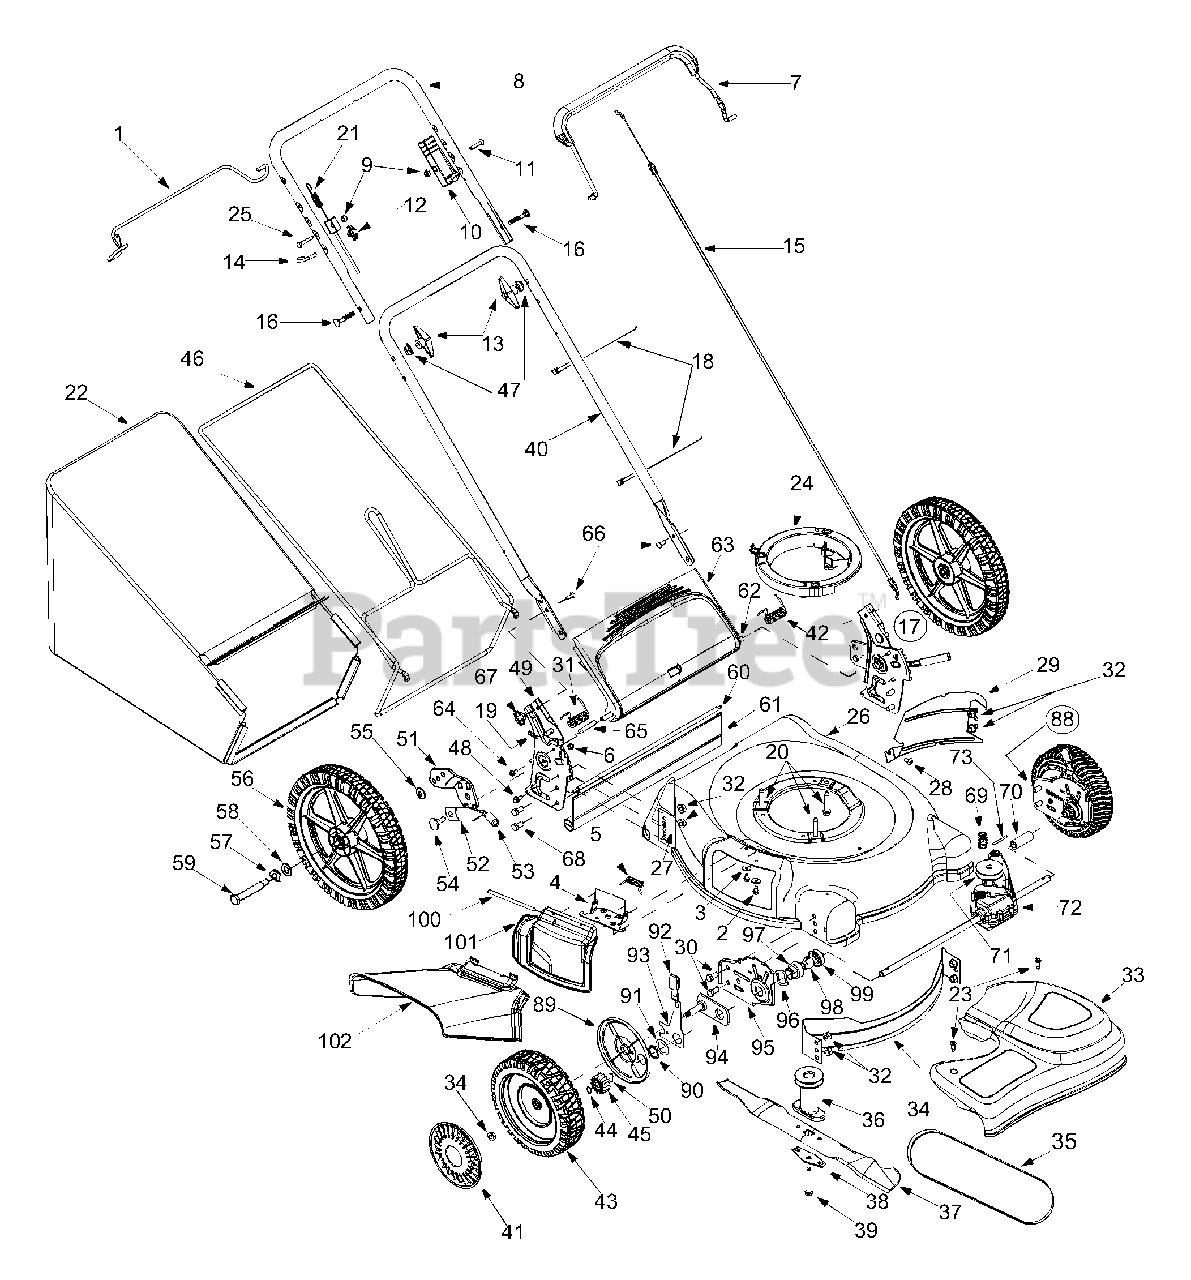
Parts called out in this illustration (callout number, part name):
2	TT Screw 1/4-20 x 0.5
3	Bell Washer.265 x 0.75
4	Chute Deflector Adapter
5	Torsion Spring
6	Lock Nut
7	Deluxe Control Lever
10	Control Housing
11	Oval C-Sunk Screw 1/4-20 x 1.31
12	Handle Knob
13	Handle Knob
14	Eye Bolt
15	Control Cable
16	Carriage Bolt 5/16-18 x 2.0
17	RH Bracket Assembly
18	Cable Tie
19	Cotter Pin
20	Self-Tapping Sems Screw
21	Drive Cable
22	Grassbag Assembly
23	Shoulder Screw # 12 -24
24	Engine Spacer
25	Hex Bolt 1/4-20 x 1.5
26	21" Deck
28	Screw AB: 1/4-14:.625
30	Hex Screw 3/8-16 x.75
31	Torsion Spring - R.H.
32	Hex Nut 3/8-16
33	Transmission Cover (Yellow)
36	Blade Adapter w/ Pulley
37	21" Mulching Blade
38	Blade Bell Support
39	Hex Screw 3/8-24 x 2.50
41	Hub Cap
42	Torsion Spring - L.H.
43	Wheel 8 x 2.125
44	Snap Ring
45	Gear 14T RH FWD
47	Saddle Washer
48	Hex Scr. w/Washer 1/4-14 x.625
49	RH Handle Bracket
50	Dowel Pin
51	RH Pivot Bar
52	Height Adj. Lever
53	Foam Grip
54	Shoulder Scr.500 Dia. x.434
55	Washer.401 x.870 x.063
56	Wheel 14 x 2
57	Spring Washer.50 I.D. x 1.0 O.D.
58	Flat Washer
59	Shoulder Screw
60	Wire
61	Rear Trailing Shield
62	Pivot Rod
63	Rear Discharge Door
64	Machine Screw
65	Spacer.375 x.50 x 1.02" Lg.
66	Carriage Bolt 1/4-20
67	Wing Nut
68	Hex Bolt 3/8-16 x 1.0"
69	Belt Tension Spring
70	Slev. Spacer 9.04" Lg.
71	Input Pulley
72	Transmission Assembly
73	Roll Pin
88	Height Adjustment Assembly RH
89	Wheel Dust Cap
90	Snap Ring
91	Washer
92	Adjustment Knob
93	Front Lever RH
94	Pivot Plate Assembly
97	Bearing Support
98	Bearing Sleeve
99	Bearing Retainer
100	Hinge Pin
101	Mulch Plug Complete
102	Chute Deflector
